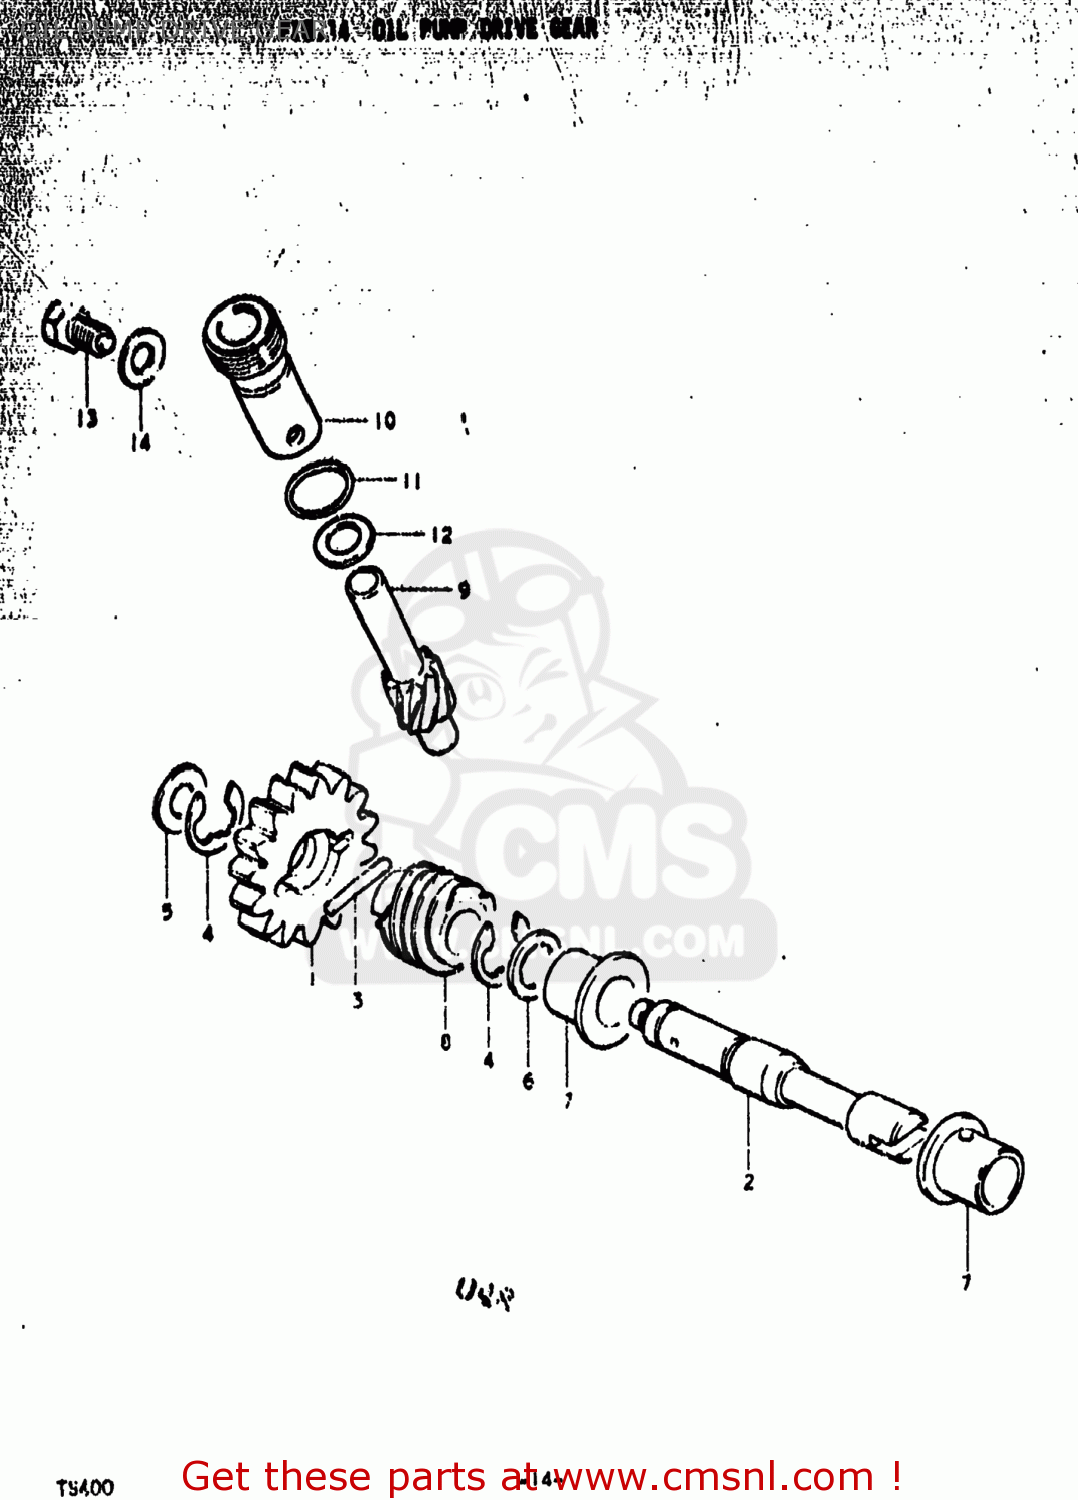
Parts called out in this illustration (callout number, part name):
1	GEAR,OIL PUMP DRIVE
2	SHAFT,OIL PUMP IDLE GEAR
3	ROLLER(4X23.8)
4	E RING
5	WASHER
6	SHIM(10X16X1)
7	BUSHING
9	GEAR,TACHOMETER DRIVEN
10	SLEEVE,TACHOMETER DRIVE
11	O RING(D:1.3,ID:9.6)
12	WASHER(8X13.7X1)
13	BOLT
14	WASHER
